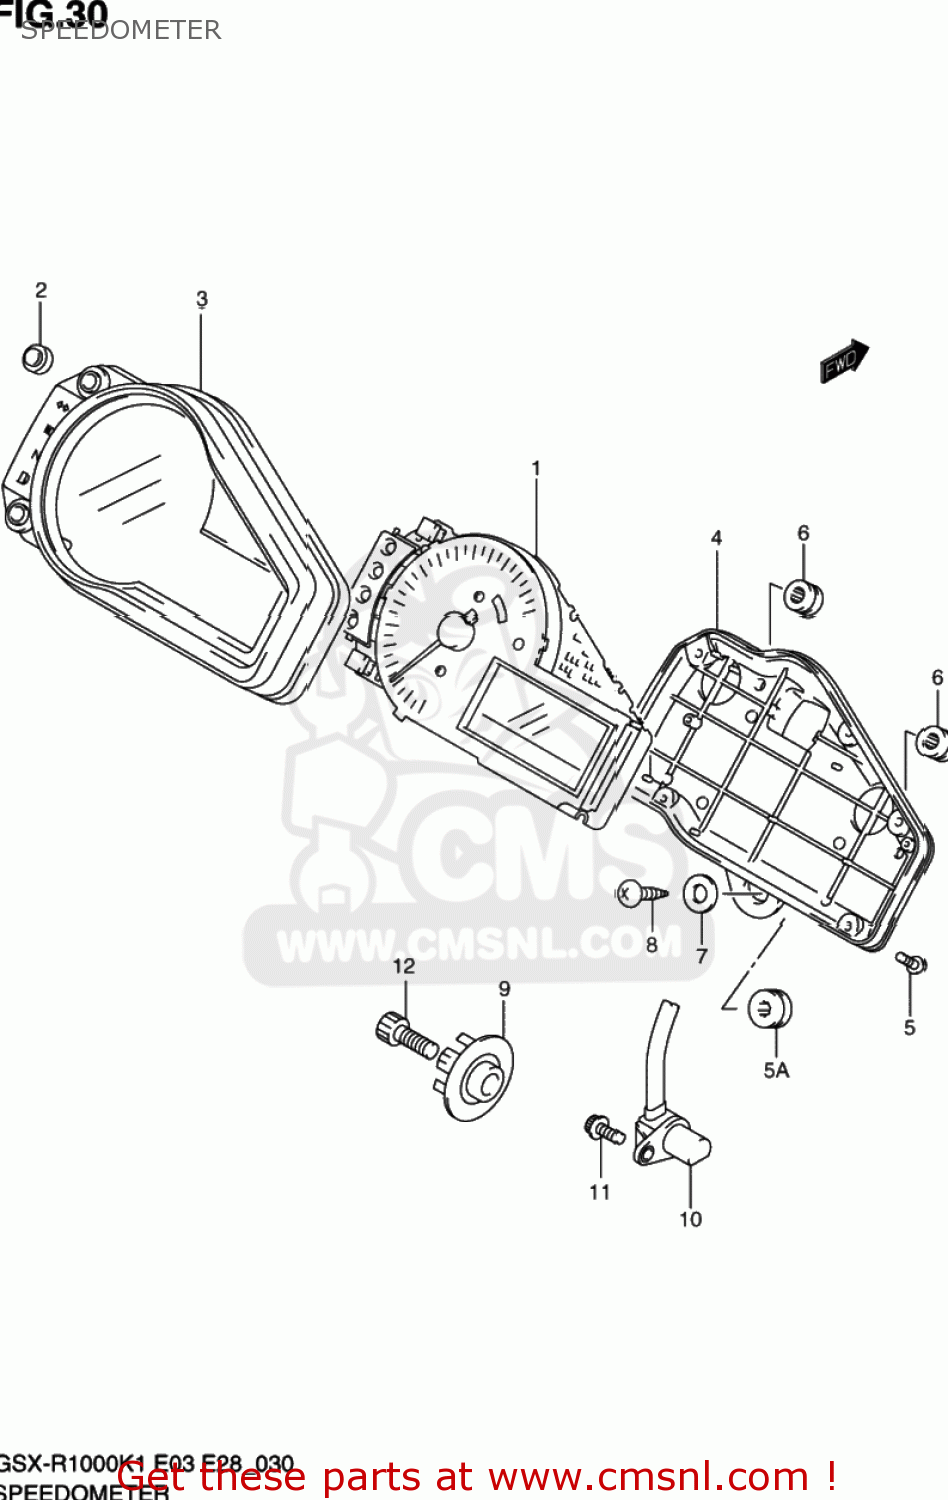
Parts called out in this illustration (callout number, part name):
1	SPEEDOMETER
2	SWITCH,LEVER
3	CASE,UPR
4	CASE,LWR
5	SCREW(3X16)
5A	CUSHION
6	CUSHION
7	WASHER(5.5X16X1.2)
8	SCREW
9	ROTOR,SPEED
10	SENSOR,SPEED
11	BOLT
12	BOLT
